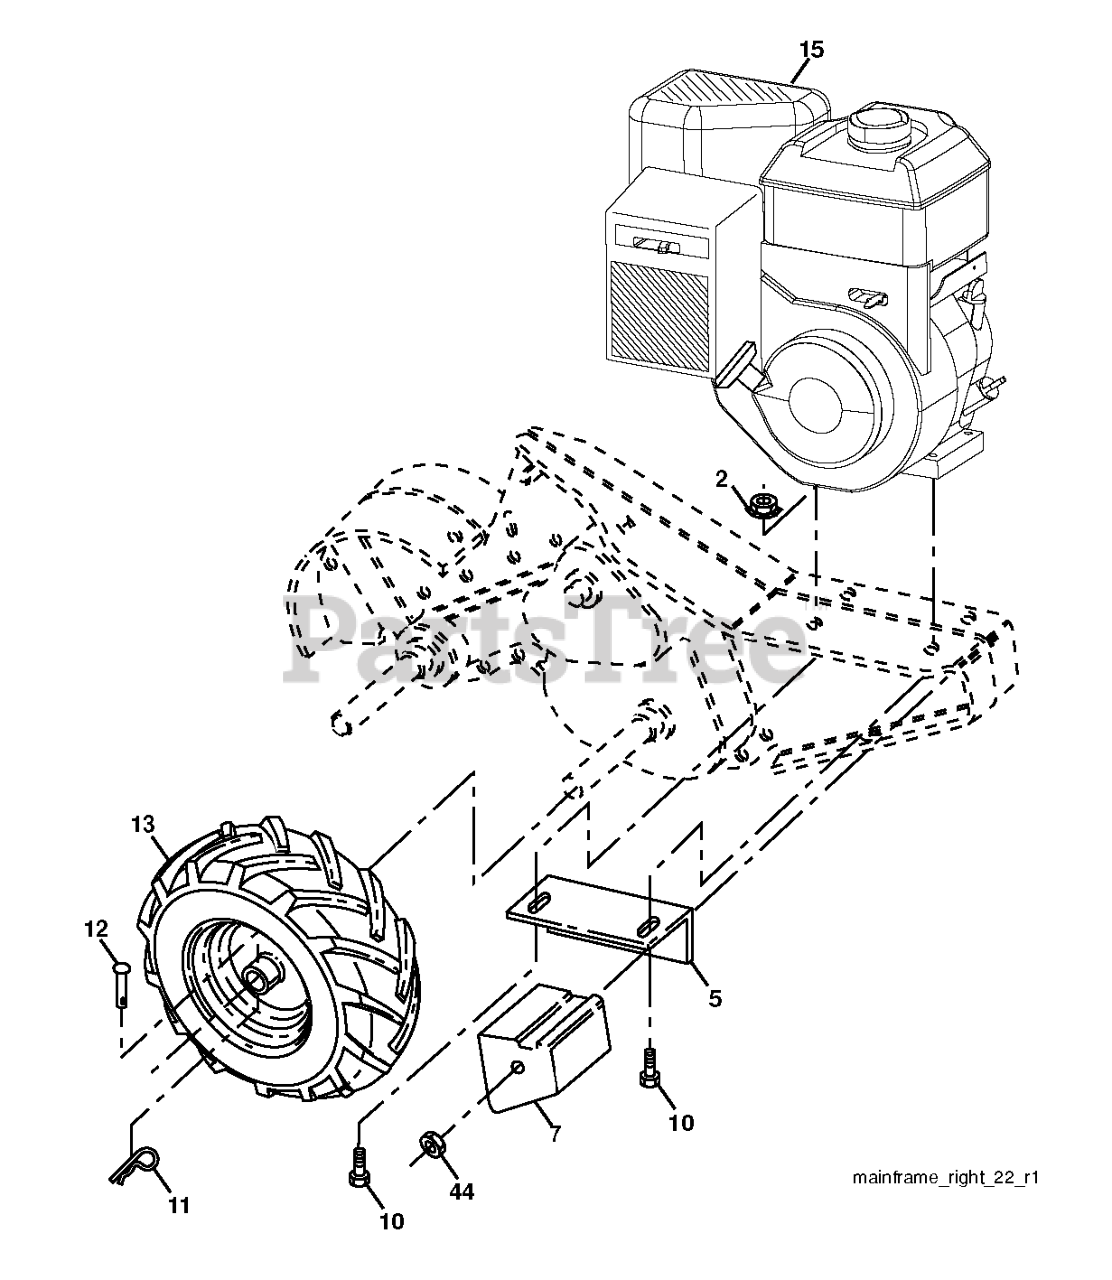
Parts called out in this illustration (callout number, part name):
2	LOCKNUT-FLANGE 5/16-18
5	BRACKET.REINFORCEMENT.RH.BLACK
7	COUNTERWEIGHT.RH
10	BOLT, HEX 5/16-18X1-3/4
11	RETAINER M
12	RIVET,DRILLED
13	WHEEL.ASM.CRT.RH.13X5X6.SILVER
